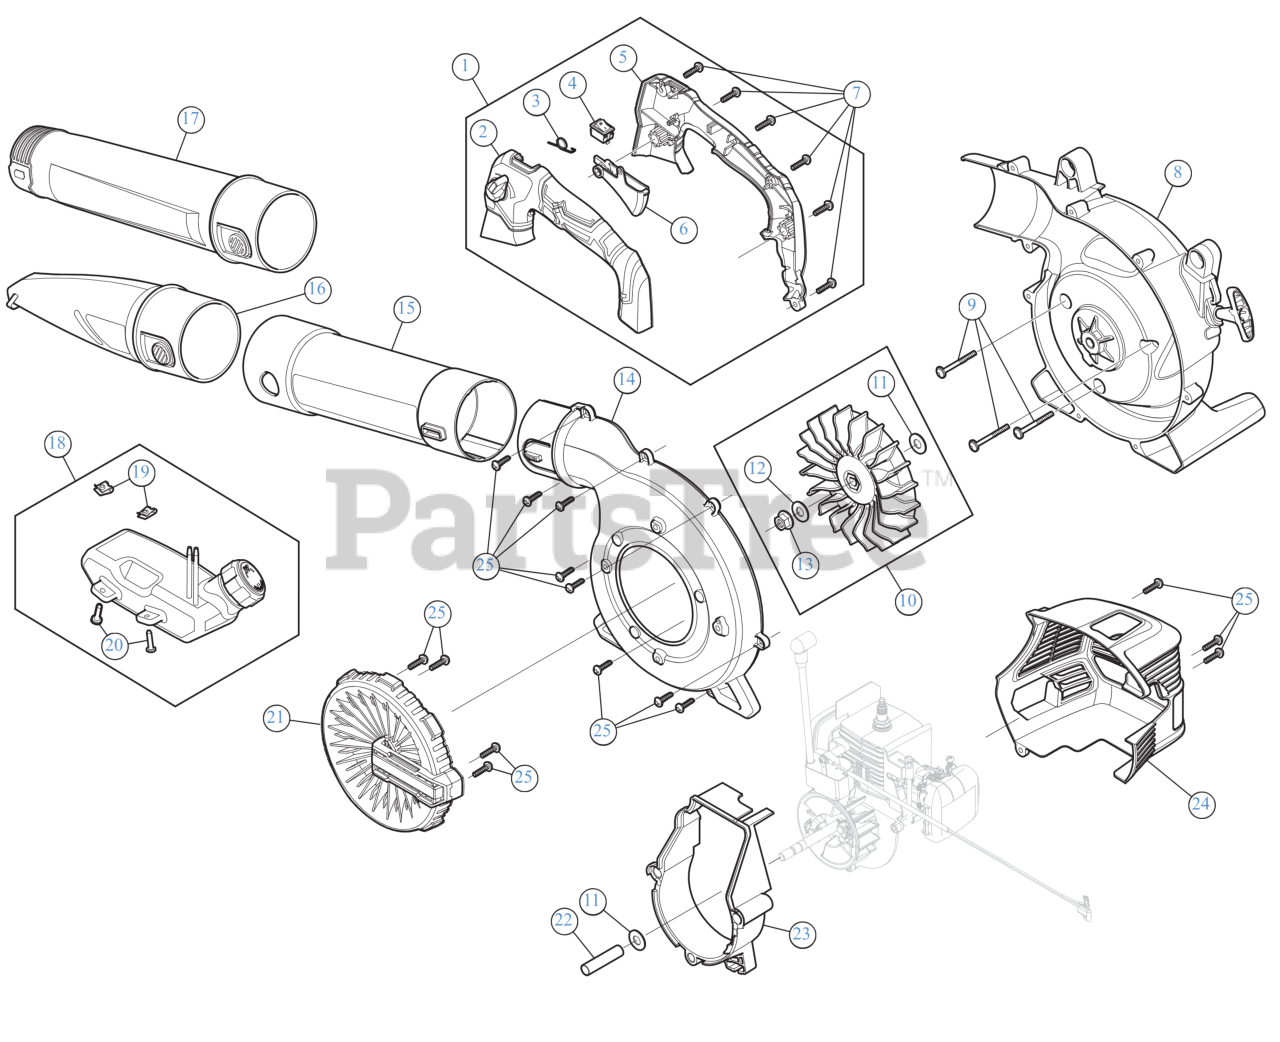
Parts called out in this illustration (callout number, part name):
1	HANDLE ASSEMBLY
2	HANDLE (LH)
3	TRIGGER SPRING
4	SW, MOMENTARY ON/O
5	HANDLE (RH)
6	THROTTLE TRIGGER
7	SCREW M5X1.8
8	IMPELLER HOUSING (RH)
9	SCREW 10/32
10	IMPELLER ASSEMBLY
11	FLAT WASHER
12	LOCK WASHER
13	NUT 3/8-24
14	IMPELLER HOUSING ASSEMBLY (OUTER)
15	TUBE UPPER
16	NOZZLE
17	LOWER BLOWER TUBE
18	FUEL TANK ASSEMBLY
19	NUT, TINNERMAN U-T
20	SCREW:10-6 x .75
21	INTAKE COVER
22	SPACER
23	ENGINE ADAPTER
24	ENGINE COVER
25	SCREW 8-16 x 3/4
